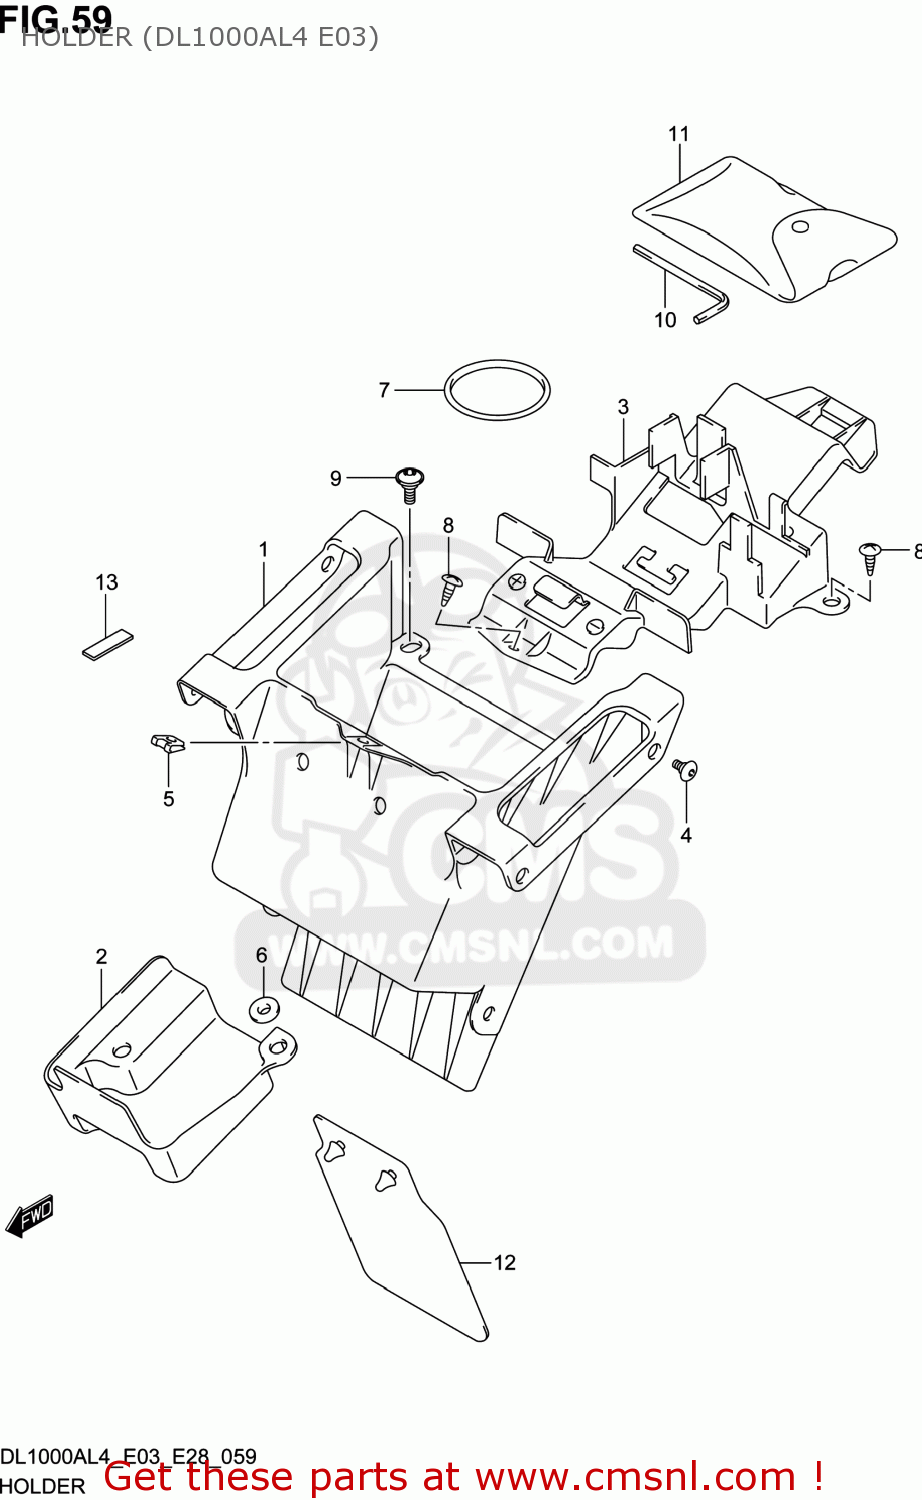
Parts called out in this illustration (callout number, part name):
1	HOLDER,BATTERY
2	COVER,ACTUATOR
3	HOLDER,TOOL
4	SCREW(6X12)
5	NUT
6	WASHER
7	O RING(D:3.5,ID:62.6)
8	SCREW
9	BOLT(5X13)
10	HEXAGON SPANNER,5
11	TOOL ASSY
12	MUDGUARD,RR FENDER
13	CUSHION,PANEL NO.2
